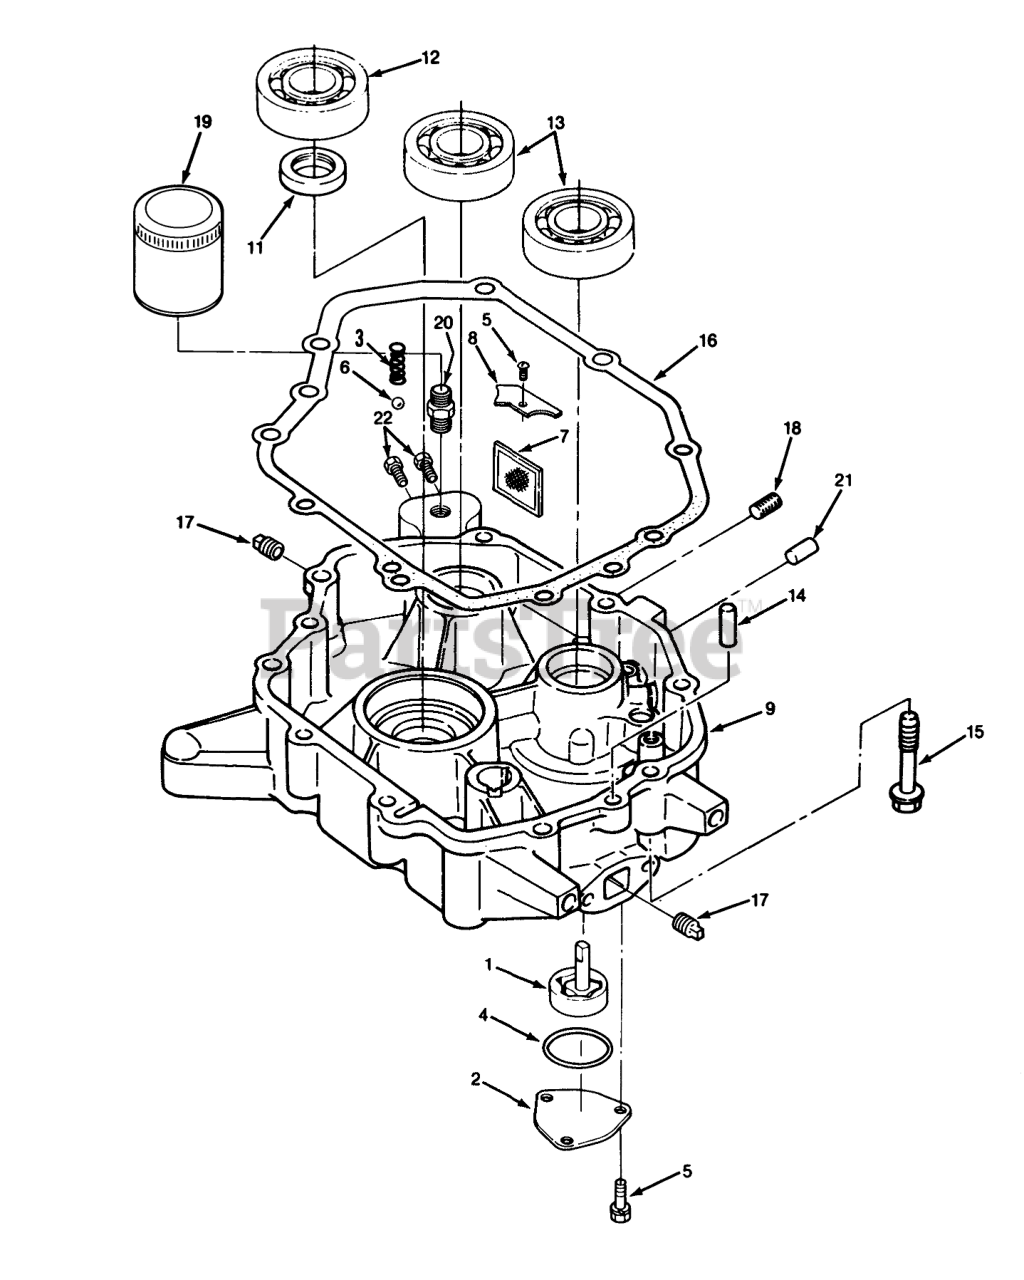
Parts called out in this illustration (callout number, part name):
1	PUMP-OIL
2	COVER-OIL PUMP
3	SPRING-RELIEF VALVE
4	RING-O
5	SCREW
6	BALL-BEARING
7	SCREEN
8	COVER
9	BASE-0IL
11	SEAL-OIL CRNKSHFT UP
12	BRNG-BALL CRANKSH L
13	BRNG-BALL BAL SHFT L
14	PIN-ALIGNMENT
15	SELF-TAP BOLT SP M8
16	Gasket
17	Plug
18	Plug
19	FILTER
20	ADAPTER
22	PLUG-HEX HD
